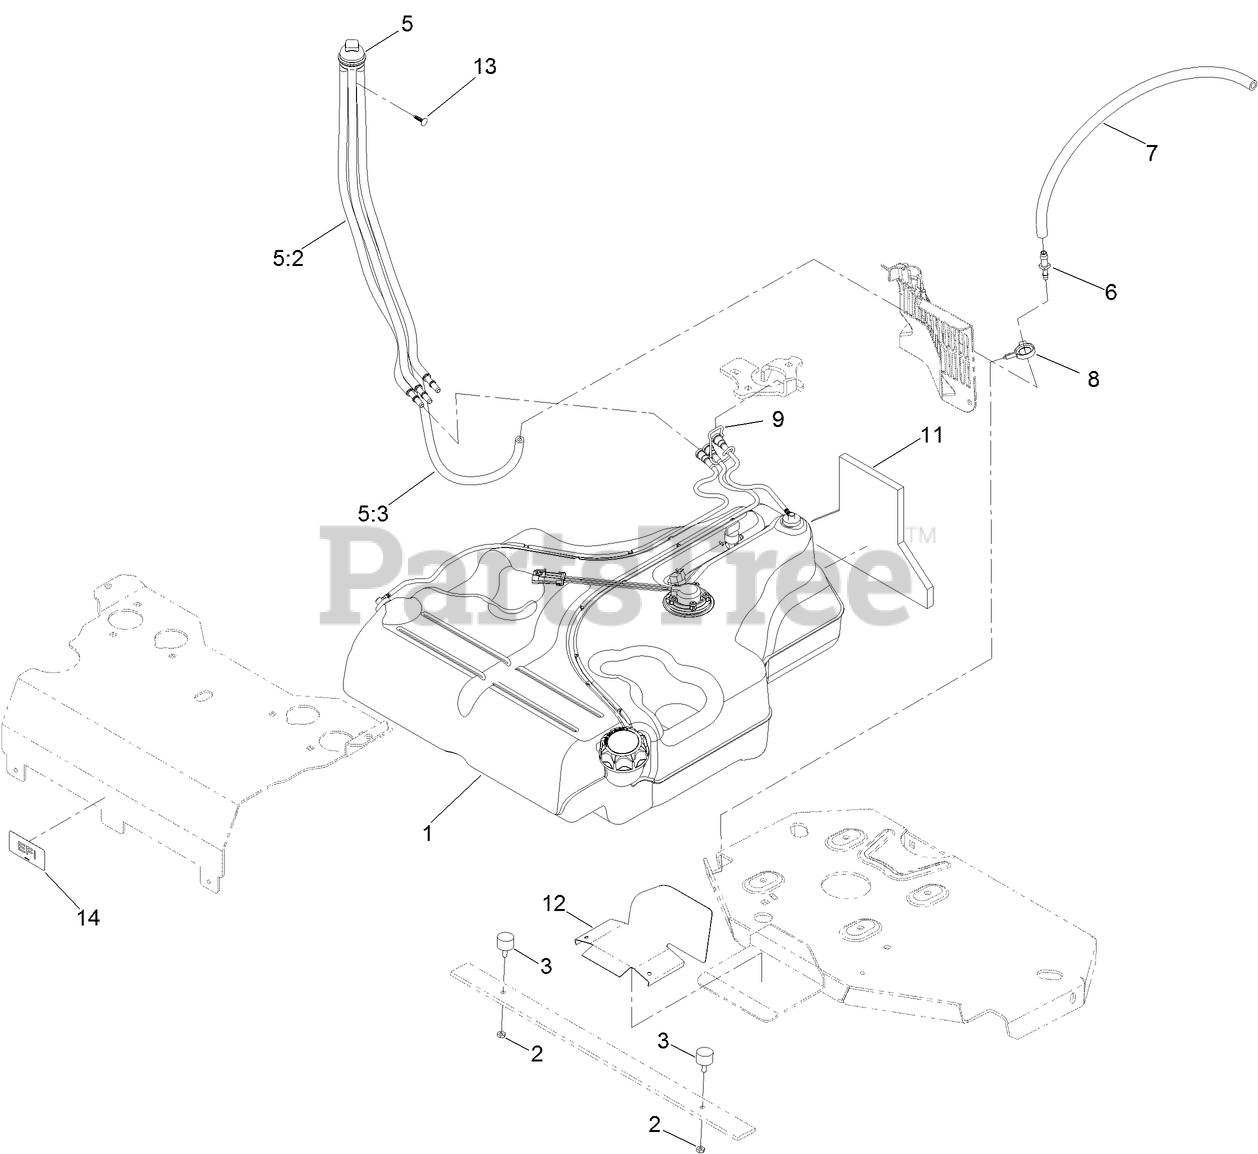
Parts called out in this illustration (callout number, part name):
1	FUEL TANK ASM
2	NUT-JAM
3	BUMPER
5	FUEL MANIFOLD VENT ASM
5:2	HOSE-FUEL
5:3	HOSE-FUEL
6	FITTING-STRAIGHT
7	HOSE-FUEL
8	CLAMP-HOSE
9	RETAINER-LINE, VAPOR
11	INSULATION-FOAM, FUEL TANK
12	GUARD-EXHAUST
13	PLUG-PLASTIC
14	DECAL-EFI
